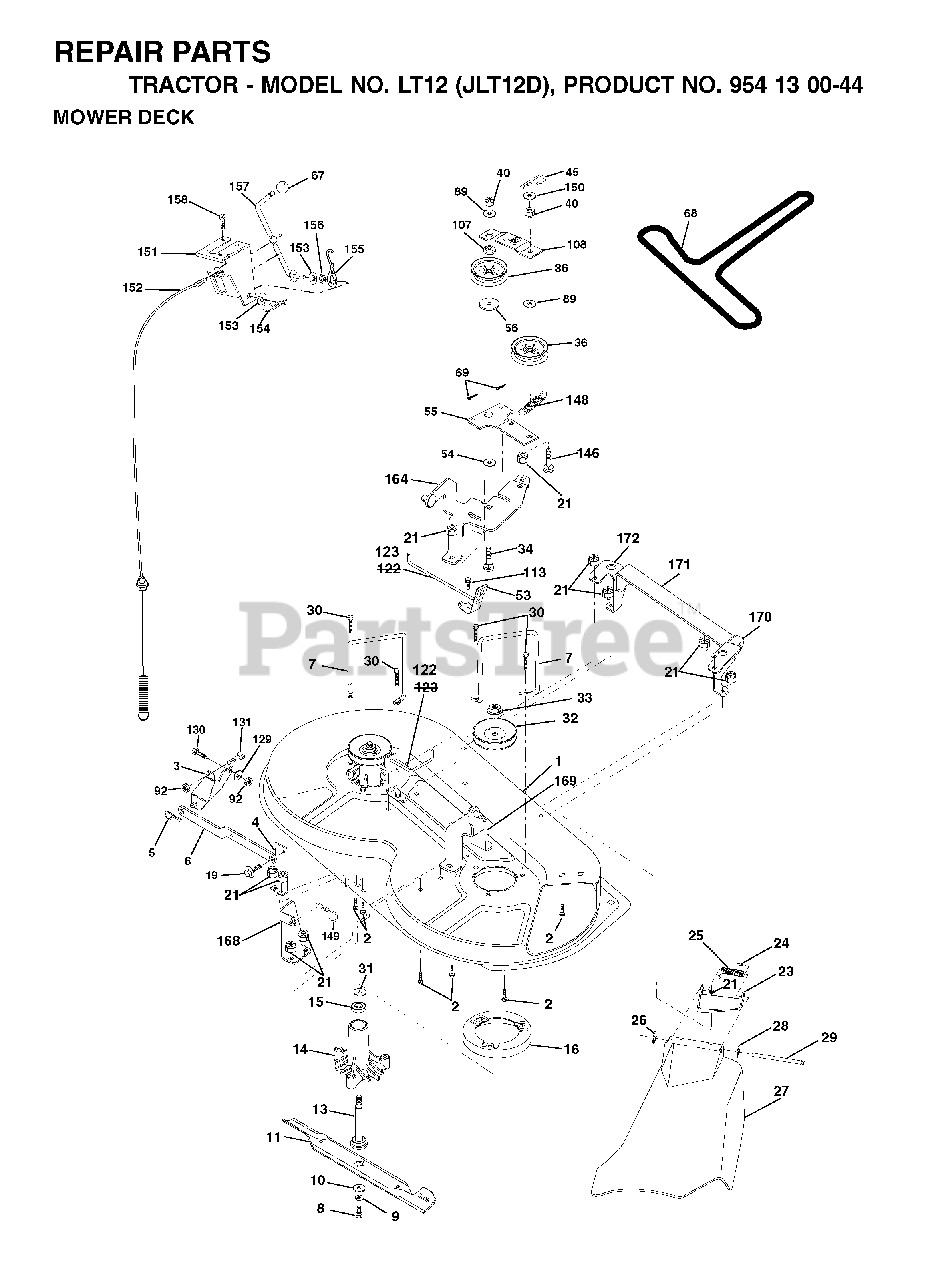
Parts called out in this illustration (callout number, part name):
2	BOLT
3	BRKT ASM SWAY BAR
5	RETAINER-SPRNG RB
6	BAR SWAY DECK
7	KEEPER LH
8	BLADE BOLT
9	LOCKWASHER
10	WASHER.BLADE
11	BLADE, HI-LIFT 36" PREMIUM
13	SHAFT ASM VENT
14	HSG MANDREL
16	STRIPPER, MWR ROUND
19	BOLT SHD 5/16-18
21	LOCKNUT
23	BRACKET ASM DEFLECTOR
24	CAP-SLEEVE LT
25	SPRING TORSION
26	NUT PUSH M
28	WASHER
29	HINGE ROD
30	SCREW, WASHER HEAD
31	WASHER
32	PULLEY, MANDREL
33	NUT, FLG TOPLOCK 9/16"
34	BOLT
36	FLAT IDLER PULLEY
40	LOCKNUT
45	RETAINER M
53	BRAKE ASSEMBLY
54	HARDENED WASHER
55	IDLER ARM
56	SPACER.RETAINER.MOWER
67	KNOB T (3/8 HOLE)
69	COTTER PIN
89	WASHER GT
92	NUT
107	SPACER.IDLER.ARM
108	STIFFENER.IDLER.ARM
129	WASHER
131	BOLT D
146	BOLT, CARRIAGE IDLER
148	IDLER RETURN SPRING
149	SPRING.RETAINER.YELLOW.ZINC
150	WASHER PM
151	BRACKET, CLUTCH CABLE
153	WASHER FLAT 3/8"
154	SPRING RETAINER
155	SPRING RETENTION LEVER
156	SPACER CLUTCH CABLE
157	ROD CLUTCH CABLE 3/8"
158	SCREW
171	BRACE
